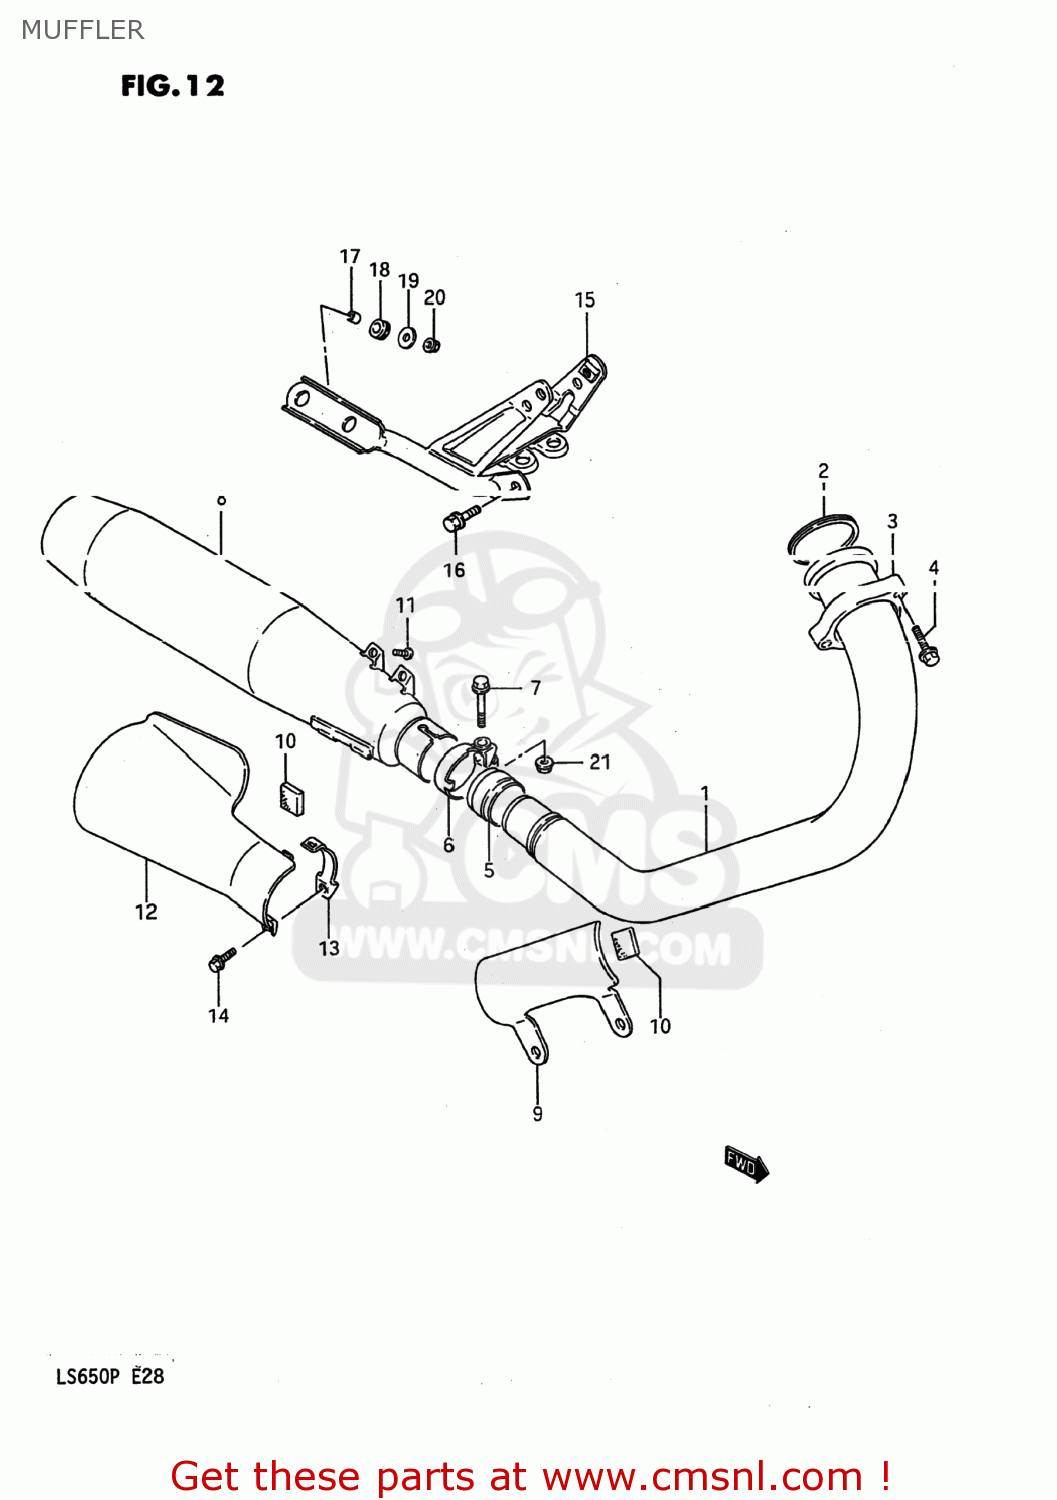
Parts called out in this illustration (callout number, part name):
1	PIPE,EXHAUST
2	GASKET,EXHAUST PIPE (NAS)
3	CLAMP,EXHAUST PIPE
4	BOLT(8X35)
5	CONNECTOR,MUFFLER
6	CLAMP,MUFFLER CONNECTOR
7	BOLT 8X40
8	BODY,MUFFLER
9	COVER,EXHAUST PIPE
10	GASKET (NAS)
11	SCREW
12	COVER,MUFFLER
13	CLAMP,MUFFLER COVER
14	BOLT 6X20
15	STAY,MUFFLER SUPPORT
16	BOLT
17	SPACER (8.8X12X11)
18	CUSHION
19	WASHER
20	NUT
21	NUT
